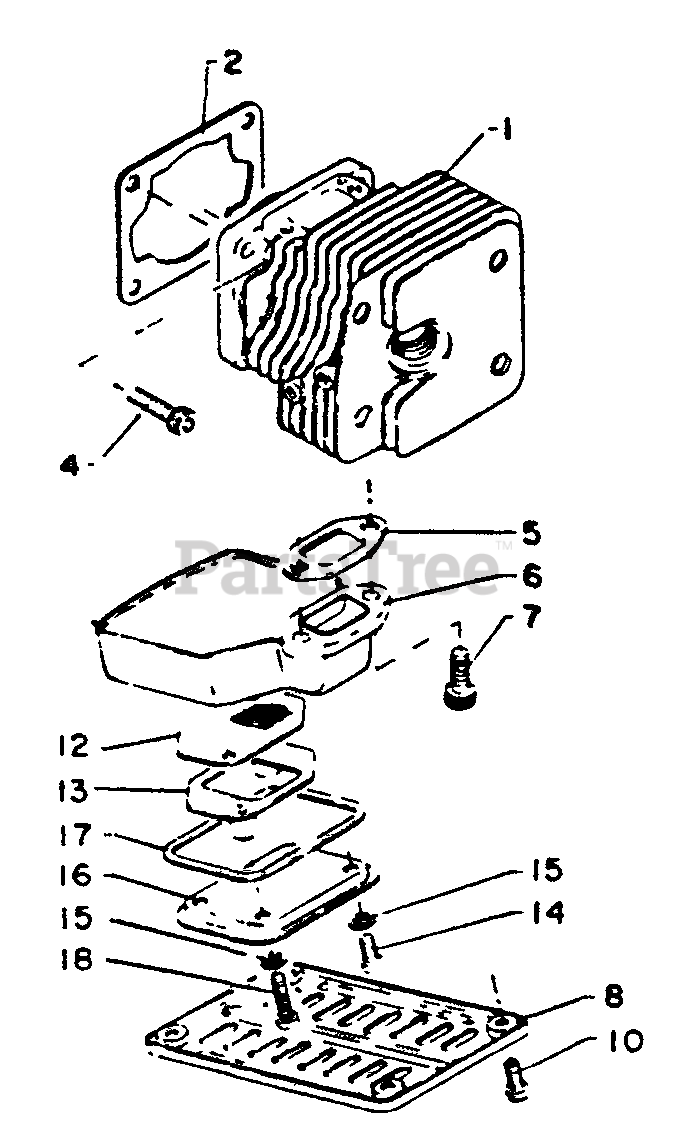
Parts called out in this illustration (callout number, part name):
1	CYLINDER
2	GASKET, CYLINDER
4	BOLT 5×20
5	GASKET, EXHAUST
6	COVER, MUFFLER
7	SCREW - 5×15
8	COVER, MUFFLER
10	SCREW - 4×10
12	SCREEN, SPARK ARRESTER
13	RETAINER, SCREEN
14	SCREW 4×6
15	WASHER, LOCK 4 MM
16	COVER, MUFFLER
17	GASKET, EXHAUST
18	SCREW 4×14
